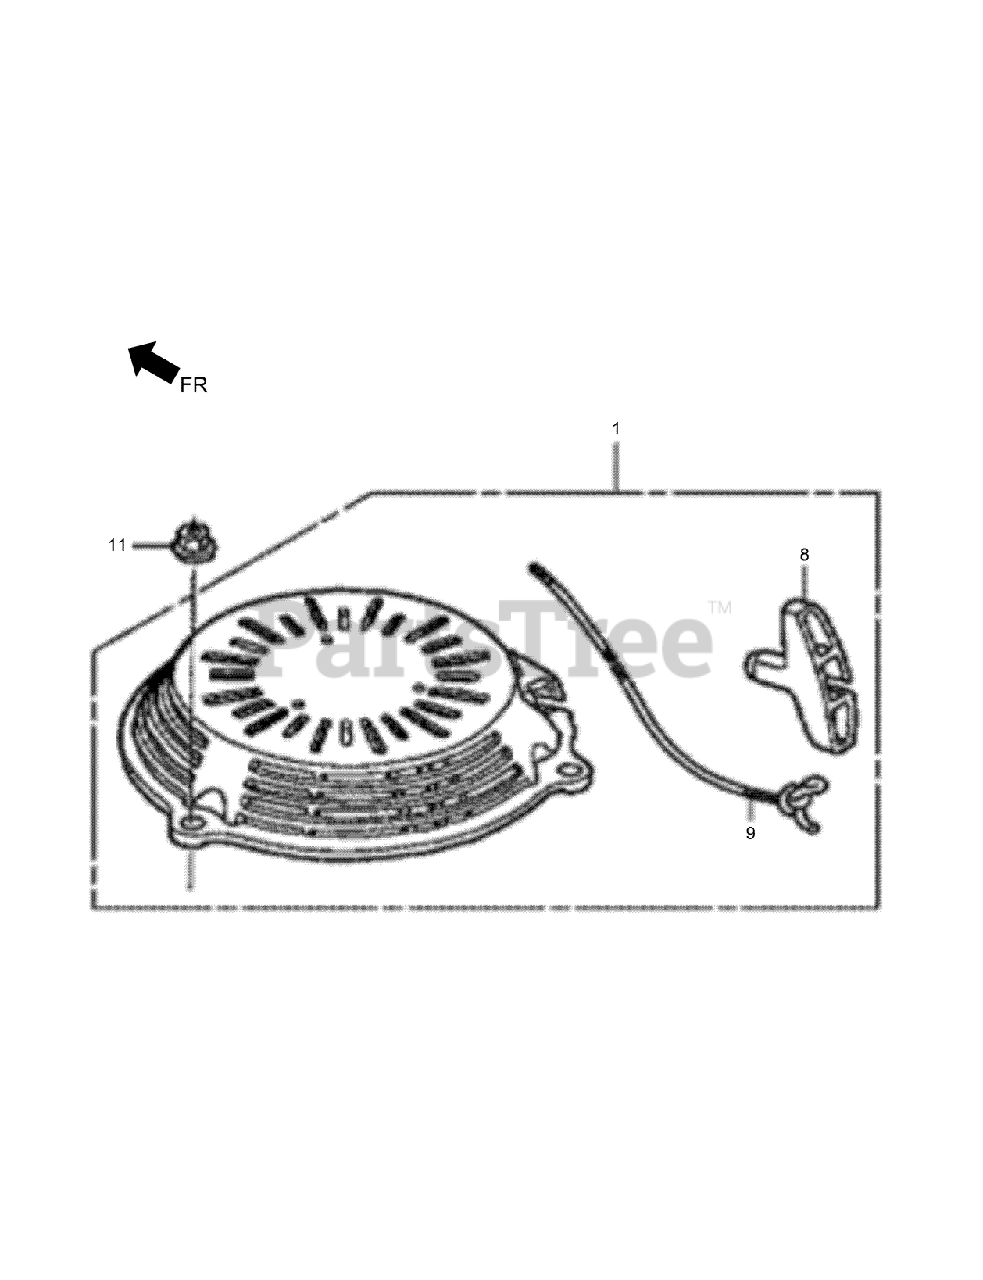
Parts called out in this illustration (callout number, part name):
1	STARTER ASM-RECOIL (NH1)
8	GRIP-STARTER
9	ROPE-RECOIL STARTER
11	NUT-FLANGE-6MM
